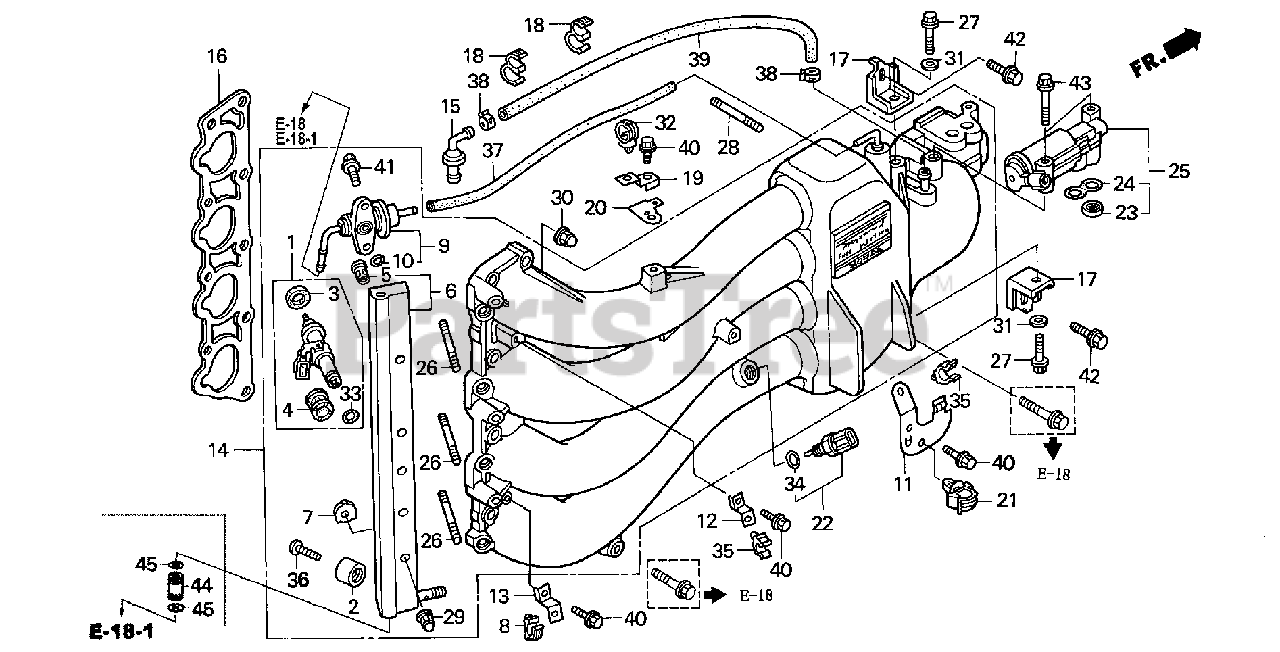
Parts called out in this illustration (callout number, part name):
1	INJECTOR SET, FUEL
1	INJECTOR SET
2	METAL, ANODE
3	SEAL RING, INJECTOR (OTSUKA)
3	SEAL RING, INJECTOR (NOK)
4	CUSHION RING, INJECTOR (OTSUKA)
4	CUSHION RING, INJECTOR (NOK)
5	MESH, FUEL FILTER
6	LINE, FUEL
7	INSULATOR, FUEL PIPE
8	CLIP, TUBE
9	REGULATOR ASSY., PRESSURE
10	O-RING, PRESSURE REGULATOR
11	BRACKET, HOSE CLAMP (A)
12	BRACKET, HOSE CLAMP (B)
13	BRACKET, TUBE CLAMP
14	MANIFOLD ASSY., IN. *NH8* (DARK GRAY)
15	VALVE ASSY., PCV
16	GASKET, IN. MANIFOLD
17	STAY, IN. MANIFOLD (A)
18	CLAMP, TUBE (7.5-11.5) (BLACK)
19	BRACKET, CLIP A
20	BRACKET, CONNECTOR (D)
21	CLAMP, WIRE
22	SENSOR ASSY., AIR TEMPERATURE
23	FILTER, ELECTRONIC AIR CONTROL VALVE (TOYO ROKI)
24	GASKET, ELECTRONIC AIR CONTROL VALVE (KEIHIN)
25	VALVE ASSY., ELECTRONIC AIR CONTROL
26	BOLT 2, STUD (6X35)
27	BOLT, SPECIAL (8X16)
28	BOLT 2, STUD (8X35)
29	NUT, CAP (6MM)
30	NUT, FLANGE CAP (10MM)
31	WASHER (14X23)
32	CLIP, HARNESS
33	O-RING (7.3X2.2) (ARAI)
35	CLAMP, PURGE HOSE
36	SCREW, PAN (6X18)
37	BULK HOSE, FUEL (3.5X3000) (3.5X340)
38	CLAMP, TUBE (D12)
39	BULK HOSE, VACUUM (7.3X1000) (7.3X370)
40	BOLT, FLANGE (6X12)
41	BOLT, FLANGE (6X14)
42	BOLT, FLANGE (8X18)
43	BOLT, FLANGE (8X45)
